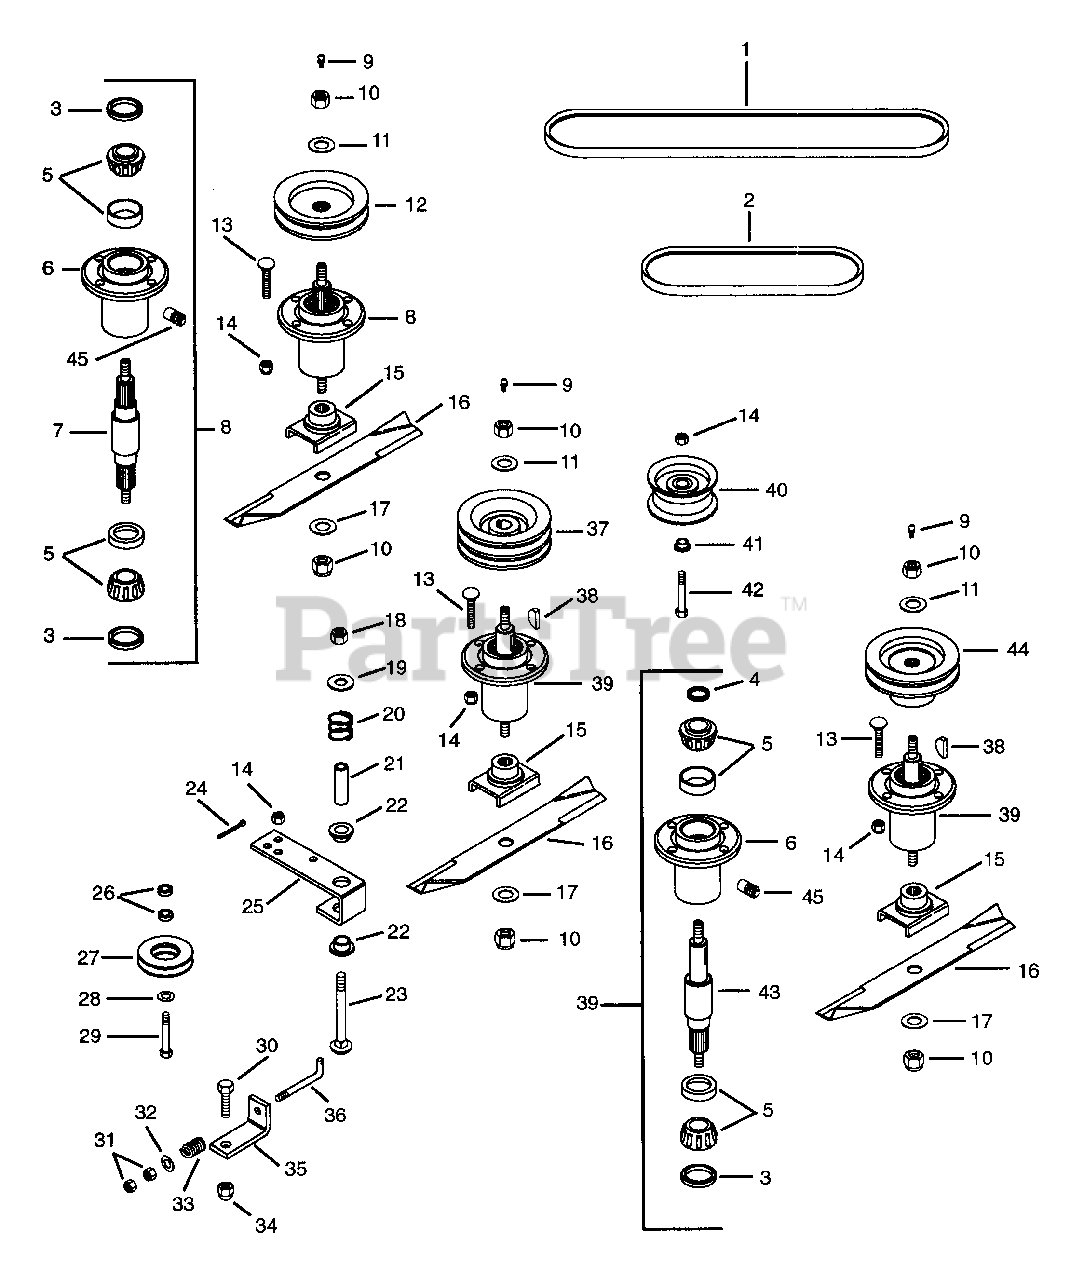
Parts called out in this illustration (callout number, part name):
1	V-Belt A-Section
2	V-Belt A-Section
3	Seal 1.987 x 1.375 x .313
4	Seal 1.987 x 1.500 x .313
5	Assembly, Bearing Cup & Cone
6	Bearing Housing
7	Shaft, Spindle
8	Service Kit Spindle Assembly
9	Fitting, Lube 1/8
10	Nut-Locking-Nylon .625-11 Grade 2
11	Washer-Flat-Steel .687 x 1.312 x .150
12	Sheave
13	Bolt-Round Head Square Neck .38-16 x 1.375
14	Nut-Locking-Nylon .375-16 Grade 2
15	Weldment, Blade Cradle
16	Blade
17	Washer-Flat-Steel .656 x 1.312 x .095
18	Nut-Locking .50-13
19	Washer-Flat-Steel .531 x 1.250 x .100
20	Spring-Compression .085 x .80 x 1.00
21	Bushing, Steel .560 x .750 x 2.44
22	Bushing-Flange .762 x 1.0 x .580 x 1.48
23	Bolt-Hex .50-13 x 3.50 Grade 5
24	Pin-Cotter .09 x .75
25	Arm, Idler Pivot
26	Bushing .406 x .750 x .188
27	Idler-V 3 x .38
28	Washer-Flat-Steel .375 x 1.125 x .065
29	Bolt-Hex .38-16 x 2.00 Grade 5
30	Bolt-Hex .50-13 x 1.25 Grade 5
31	Nut-Hex .375-16 Grade 2
32	Washer-Flat-Steel .406 x .812 x .065
33	Spring-Compression .125 x .78 x 1.00
34	Nut-Locking-Nylon .50-13 Grade 5
35	Bracket, Belt Tensioner
36	Rod, Idler
37	Sheave
38	Key, Woodruff .25 x 1
39	Service Kit Spindle Assembly
40	Pulley-Flat 4.0 x .38
41	Bushing-Sleeve .377 x .503 x .88
42	Bolt-Hex .38-16 x 3.00 Grade 5
43	Shaft, Spindle
44	Sheave
45	Relief Fitting
